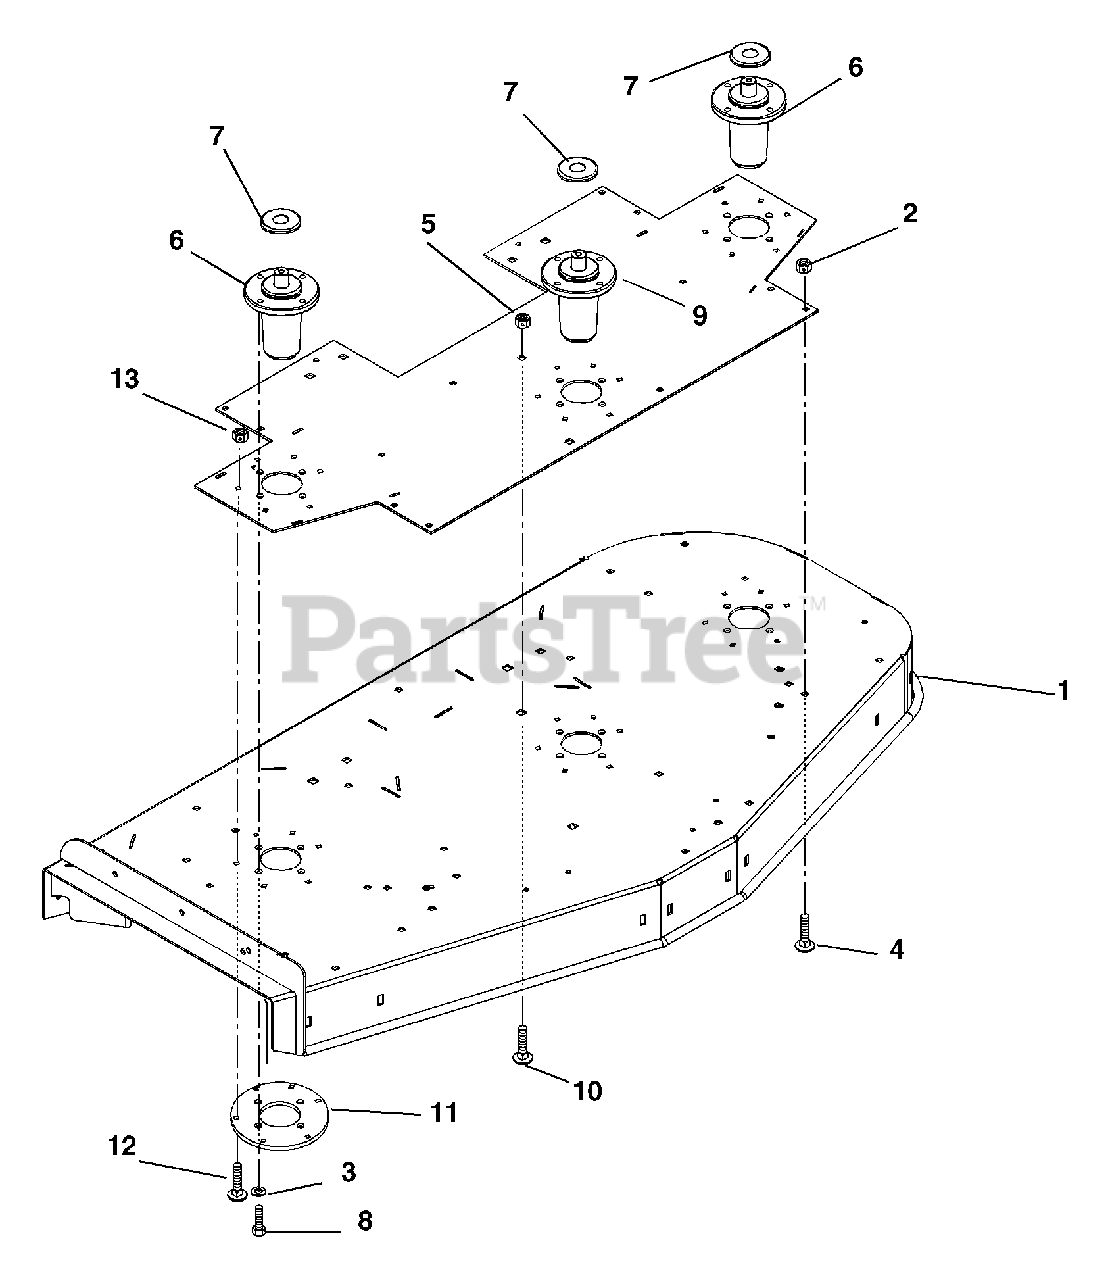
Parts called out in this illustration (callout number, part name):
1	Weldment, 72" Deck (Side Discharge)
2	Plate, 72" Reinforcment
3	Washer-Locking .38 x .094
4	Bolt-Round Head Square Neck .38-16 x 2.75 Grade 5
5	Nut-Locking-Nylon .38-16
6	Assembly, Spindle L-Hub
7	Slinger-Dust
8	Bolt-Hex .38-16 x 1.00 Grade 5
9	Assembly, Spindle
10	Bolt-Round Head Square Neck .38-16 x 1.00 Grade 2
11	Plate, Spindle Reinforcement
12	Bolt-Round Head Square Neck .38-16 x 1.00 Grade 5
13	Nut-Locking-Center .38-16
